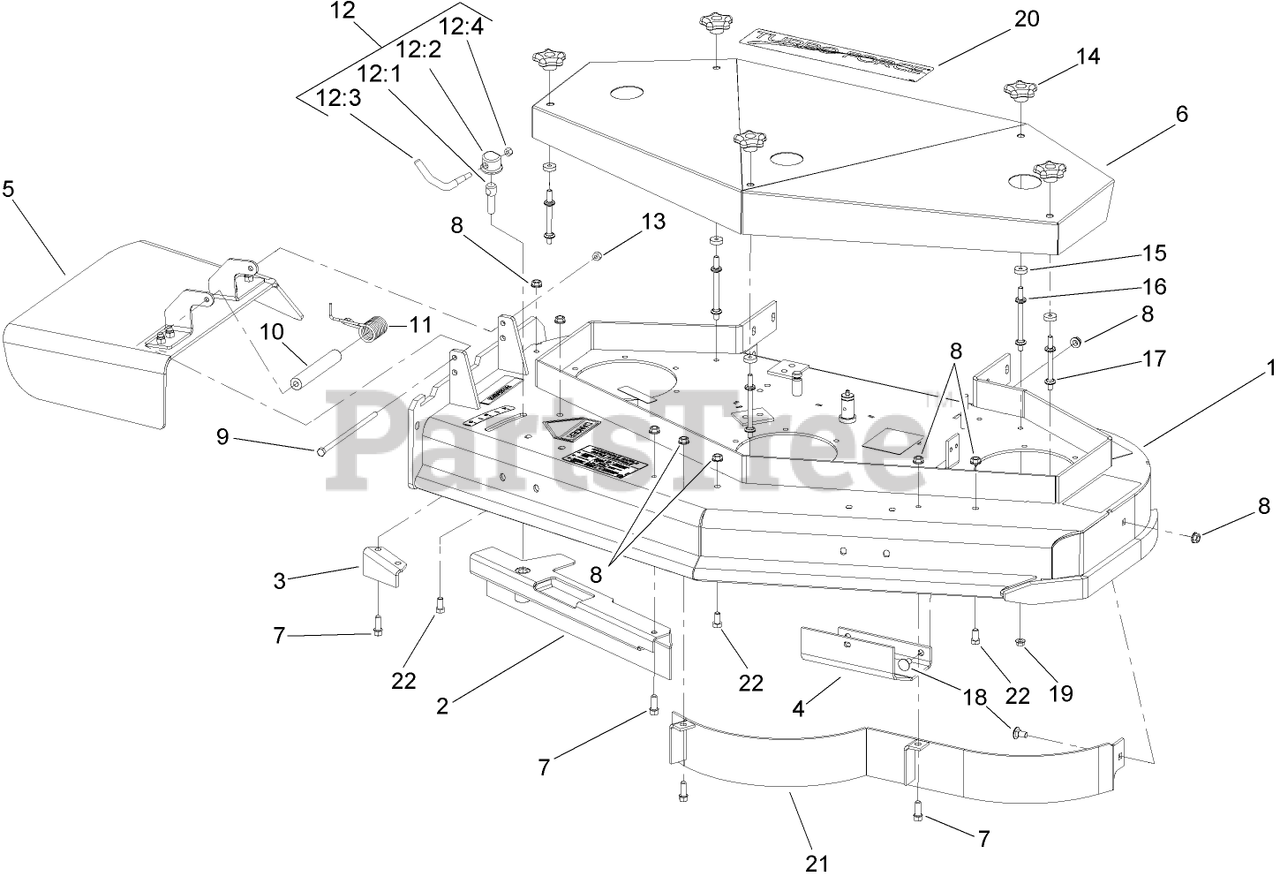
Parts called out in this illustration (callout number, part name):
1	DECK ASM
2	ADJUSTABLE BAFFLE
3	BAFFLE-DISCHARGE
5	DEFLECTOR ASM
7	SCREW-HWH
8	NUT-HHF, WHIZ
9	SCREW-HH
10	SPACER
11	SPRING-TORSION
12	LEVER ASM
12:1	Screw-Lock
12:2	CAP-LOCK
12:3	Lever-Lock
12:4	NUT-LOCK, NI
13	NUT-LOCK, NI
14	KNOB-HANDLE
15	WASHER
16	STUD-SHIELD, BELT (LONG)
17	STUD-SHIELD, BELT (SHORT)
18	SCREW-CARR
19	NUT-HF
20	DECAL
21	BAFFLE ASM
22	SCREW-HH
